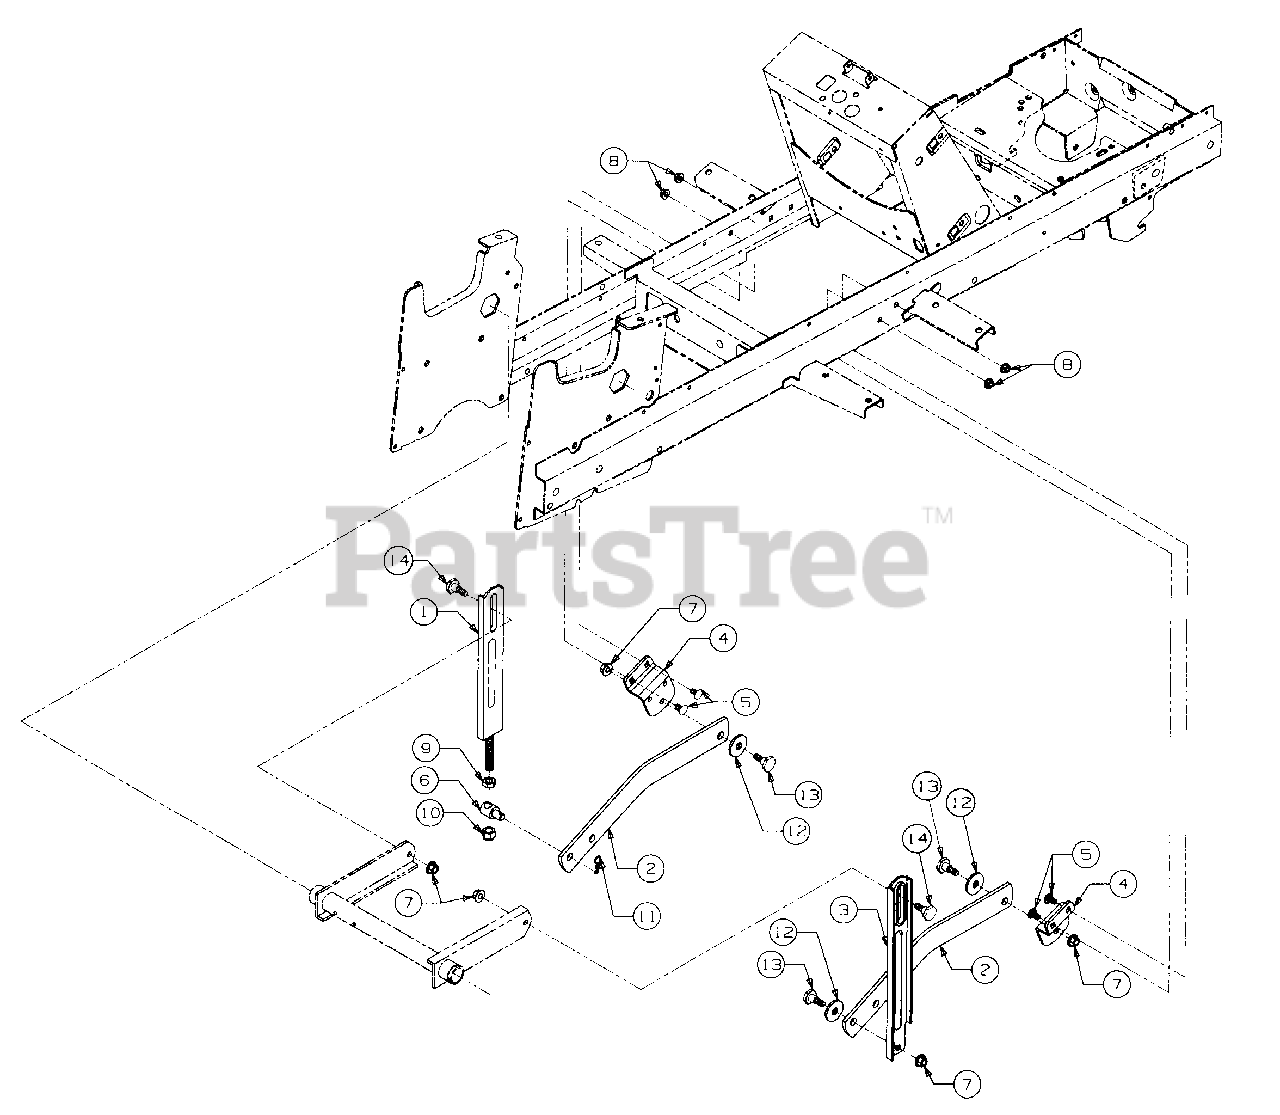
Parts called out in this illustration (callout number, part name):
2	Link, Lift
5	Bolt, Carriage, 5/16-18 x .62 Lg
6	Ferrule, Adjustment
7	Nut, Hex Flanged Lock, 3/8-16
8	Nut, Hex Flange Top Lock 5/16-18
9	Nut, Hex Jam, 1/2-13 GR5
10	Nut, Hex Top Nylon Lock 1/2-13
11	Pin, Internal Cotter, .092 Dia x 1.63 Lg
12	Washer, Flat, .50 x 1.5 x .15 Thk
13	Bolt, Shoulder
14	Bolt, Shoulder
